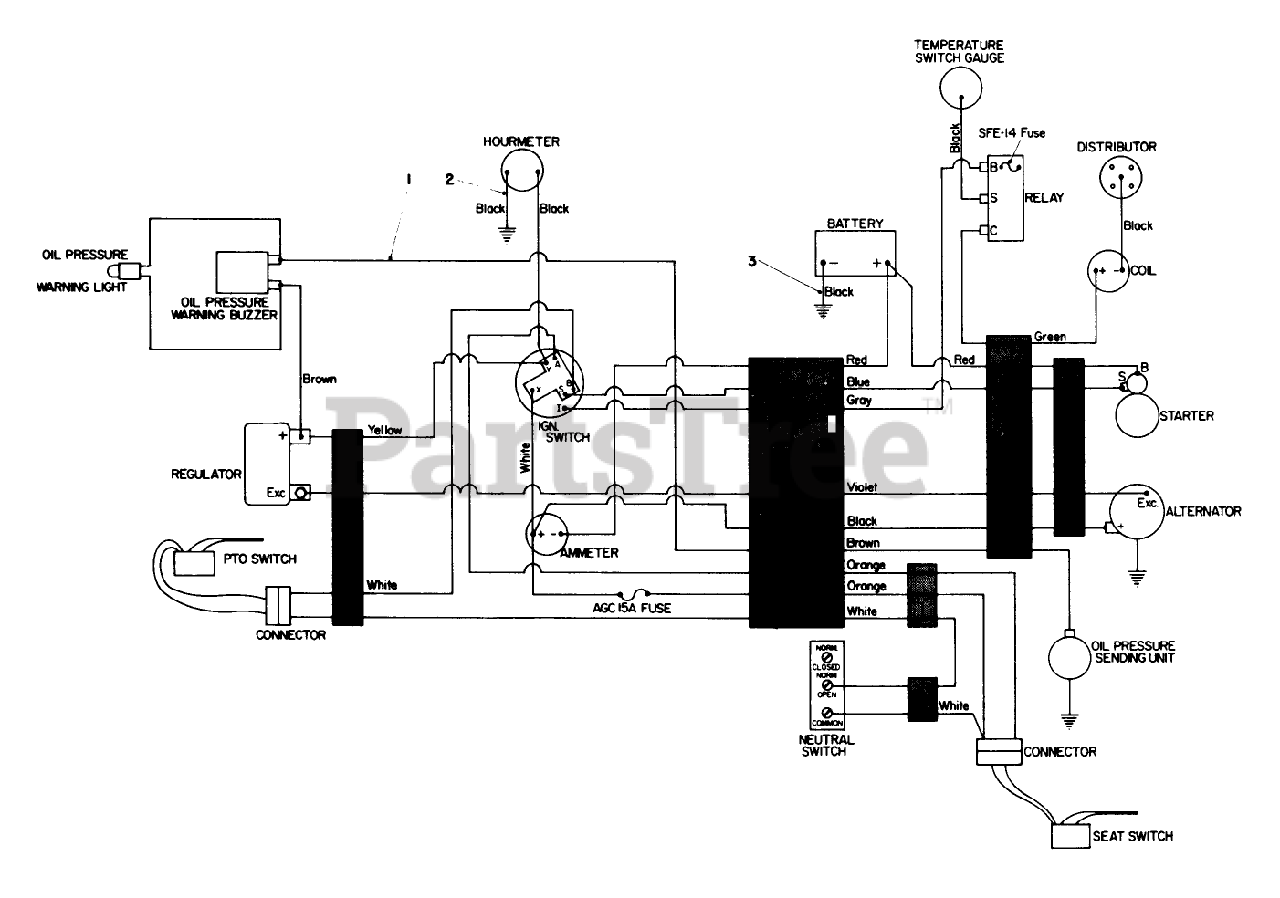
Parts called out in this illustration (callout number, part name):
1	WIRING HARNESS
2	Wire Harness
3	Cable Ground
